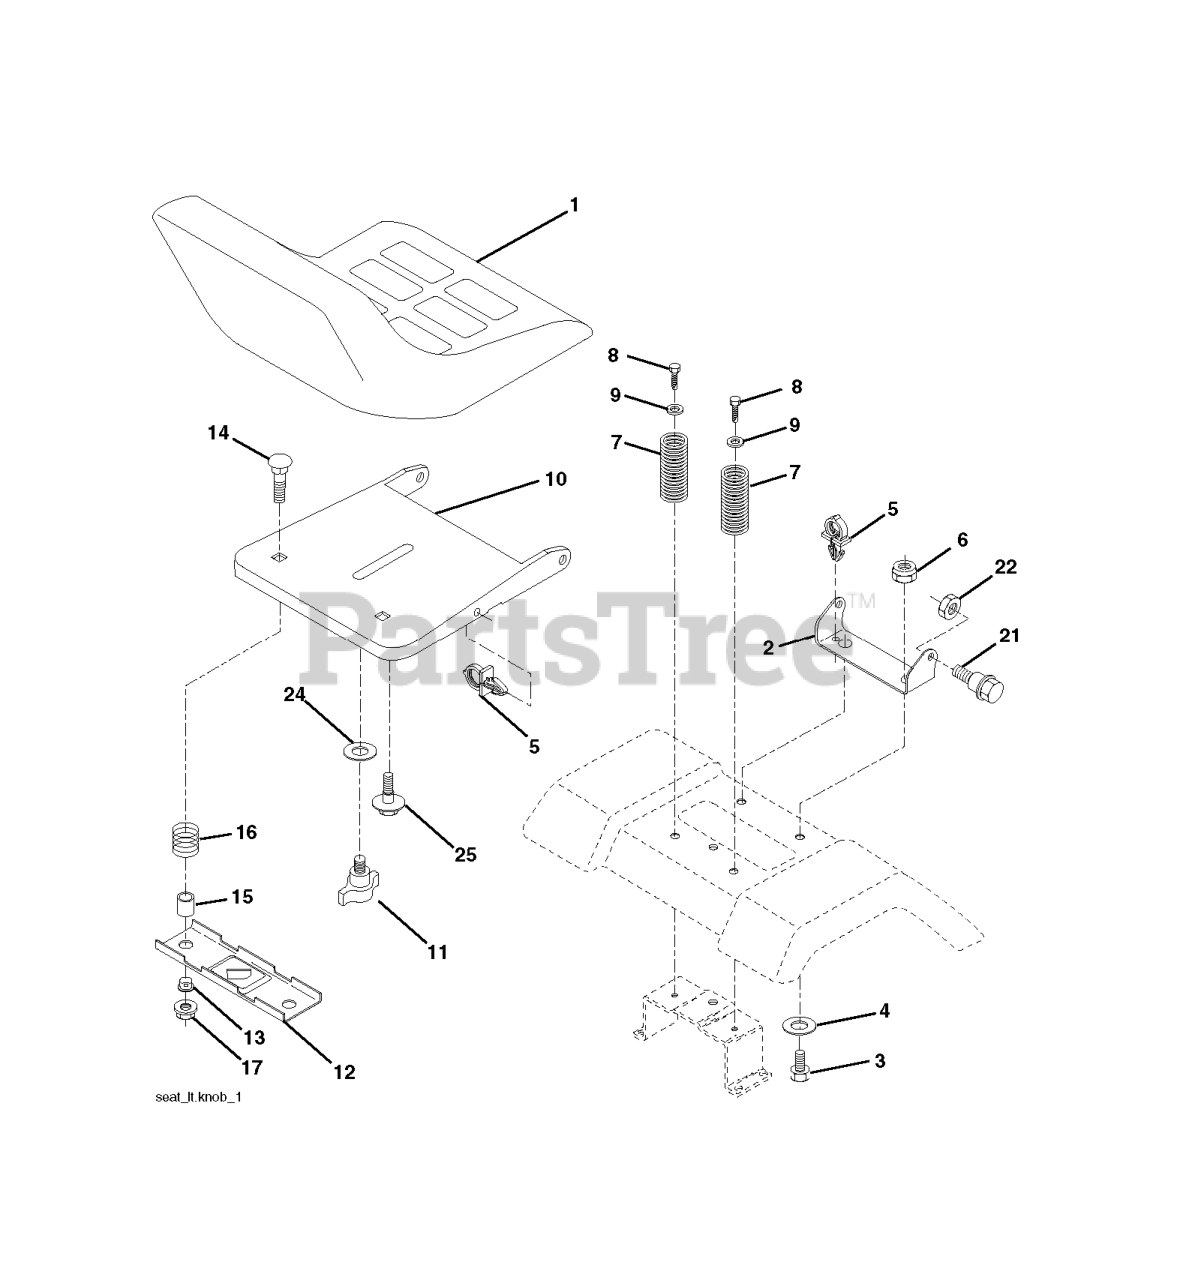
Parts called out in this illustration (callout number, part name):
1	SEAT.XH150.GRY
3	BOLT, HEX 3/8-16X1
6	NUT
7	SPRING COMPRESSION
8	SCREW 3/8-16X1
9	WASHER
10	PAN.ASM.SEAT.1SLOT
11	KNOB.SEAT.ADJ.WINGNUT
12	BRKT.MNTNG.SWITCH.SEAT.BLACK
14	BOLT.ROUND.HEAD.SQUARE.NECK
15	SPACER SPLIT
16	SPRING COMPRESSED
17	NUT T
21	BOLT.SHOULDER.5/16-18
22	NUT.71038.31-18.HEX.NYLOCK
25	BOLT,SHOULD
